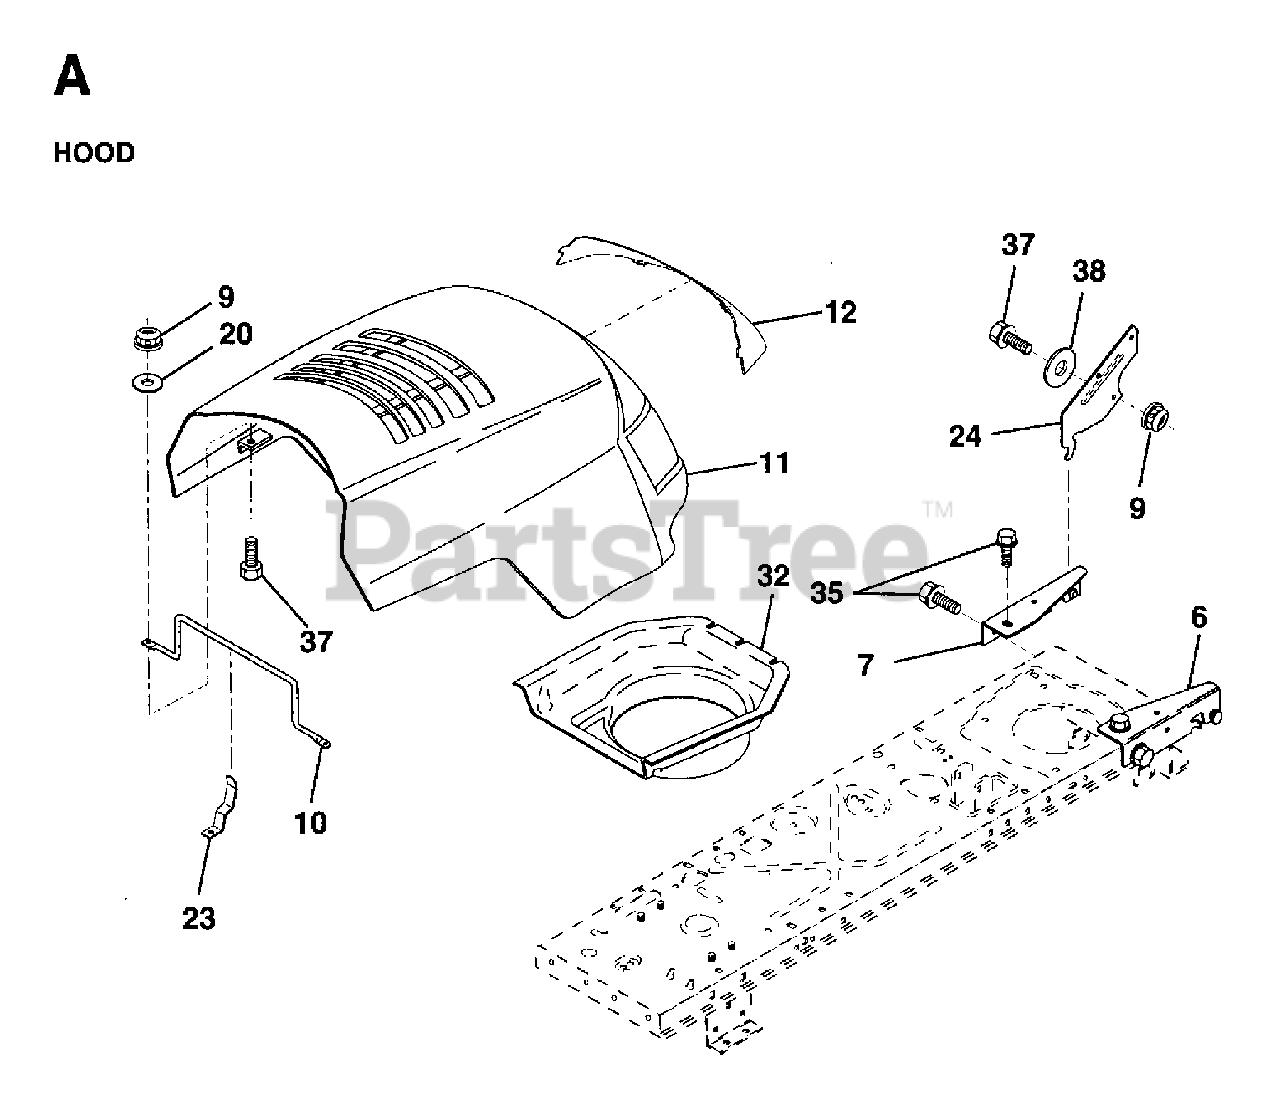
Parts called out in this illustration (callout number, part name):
6	BRACKET ASSY HOOD
7	BRACKET ASSY
9	LOCKNUT
20	WASHER
23	HOOD LATCH
35	SCREW
37	BOLT
